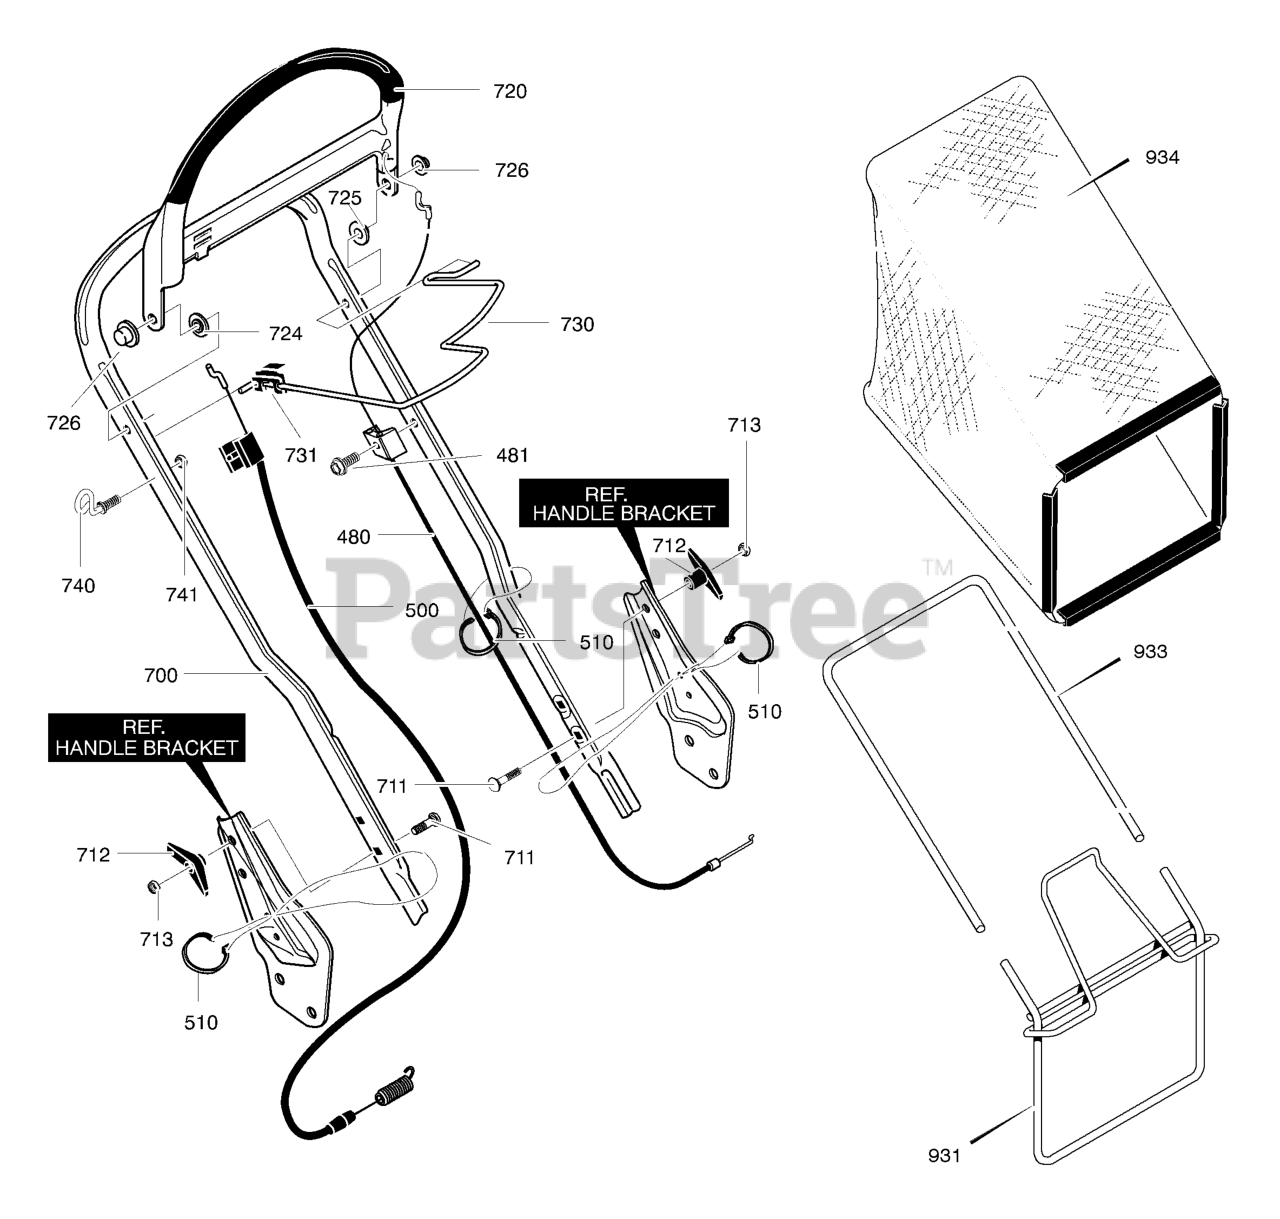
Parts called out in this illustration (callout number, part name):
480	CABLE, STOP
481	SCREW, 10-16X.75
500	CABLE, DRIVE
510	TIE, CABLE
711	BOLT, 5/16-18X2.00
712	KNOB, T NUT
713	NUT, 5/16-18
720	LEVER, STOP FLAT
726	NUT, PUSH ON
730	LEVER, DRIVE WIRE
731	BRACKET, STOP
740	GUIDE, ROPE 1/4-20
741	NUT, 1/4-20
931	BAG, FRAME ASSY.
933	FRAME, CATCHER BAG
934	BAG, CATCHER
